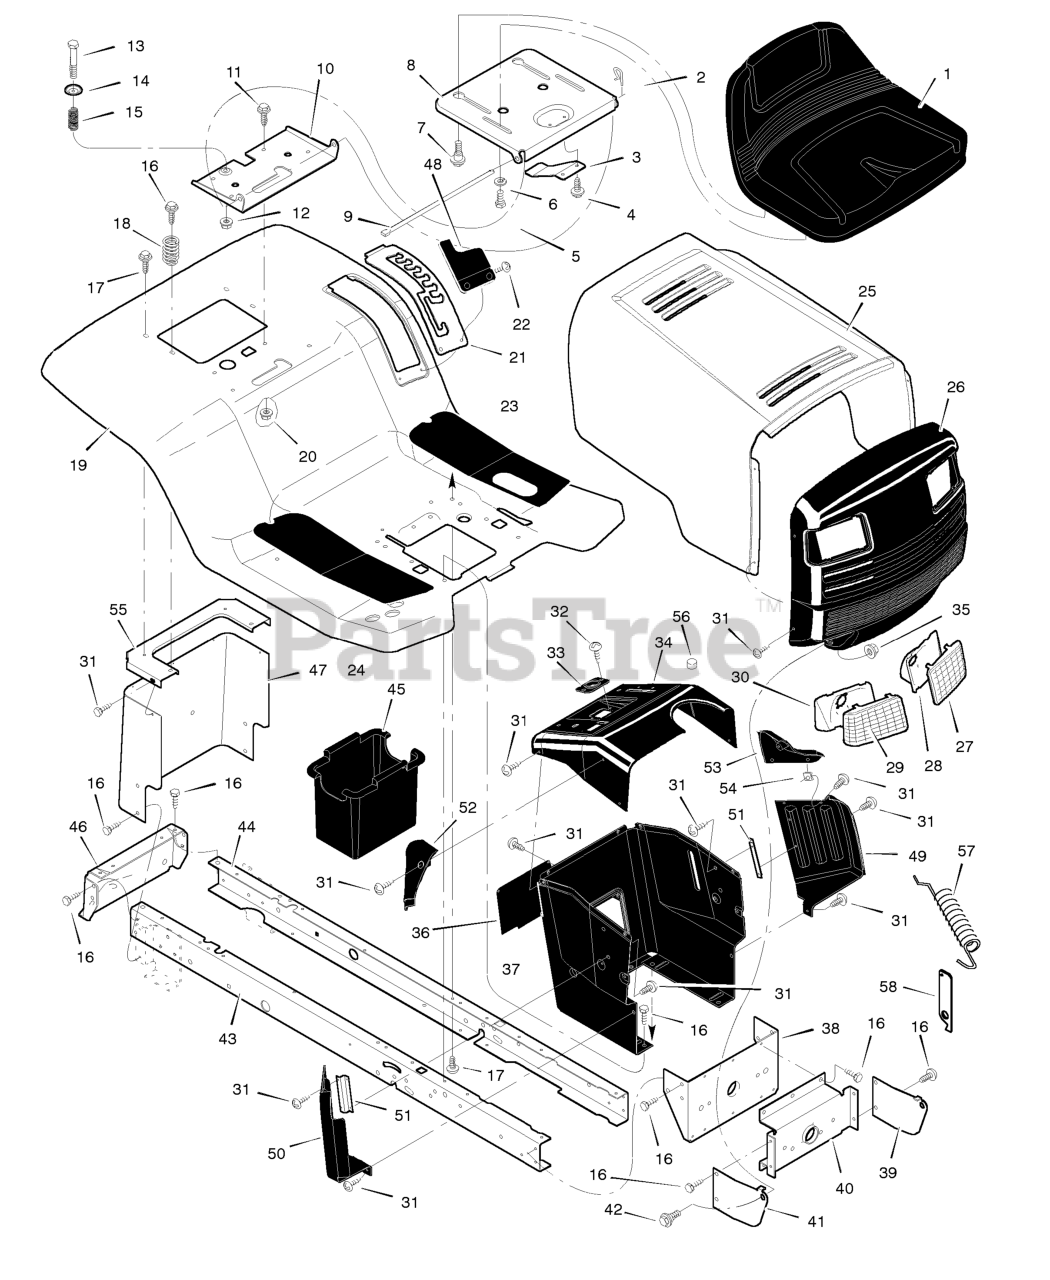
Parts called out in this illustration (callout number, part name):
2	Cap, Push On
5	Bolt, Wing
6	Washer
7	Bolt, Shoulder
8	Support, Seat
9	Rod, Pivot
10	Bracket, Pivot
11	Bolt
13	Bolt, Shoulder
15	Spring
19	Deck, Seat
20	Nut
21	Plate, Index
23	Mat, Left
24	Mat, Right
27	Lens, Left
28	Bezel, Left
29	Lens, Right
30	Bezel, Right
31	Screw
33	Bearing, Steering
35	Nut
36	Panel, Access
37	Support, Dash
38	Bracket, Rear Hanger
39	Support, Left Grille
40	Axle, Hanger
41	Support, Right Grille
42	Bolt, Shoulder
43	Frame, Right
44	Frame, Left
45	Container, Battery
46	Plate, Hitch
47	Panel, Rear
48	Cover, Level Adjustment
49	Panel, Left Side
50	Panel, Right Side
51	Bracket, Panel
52	Cap, Panel
53	Cap, Left Panel
54	Retainer
55	Plate, Rear
56	Bumper
57	Extension, Spring
58	Bracket
